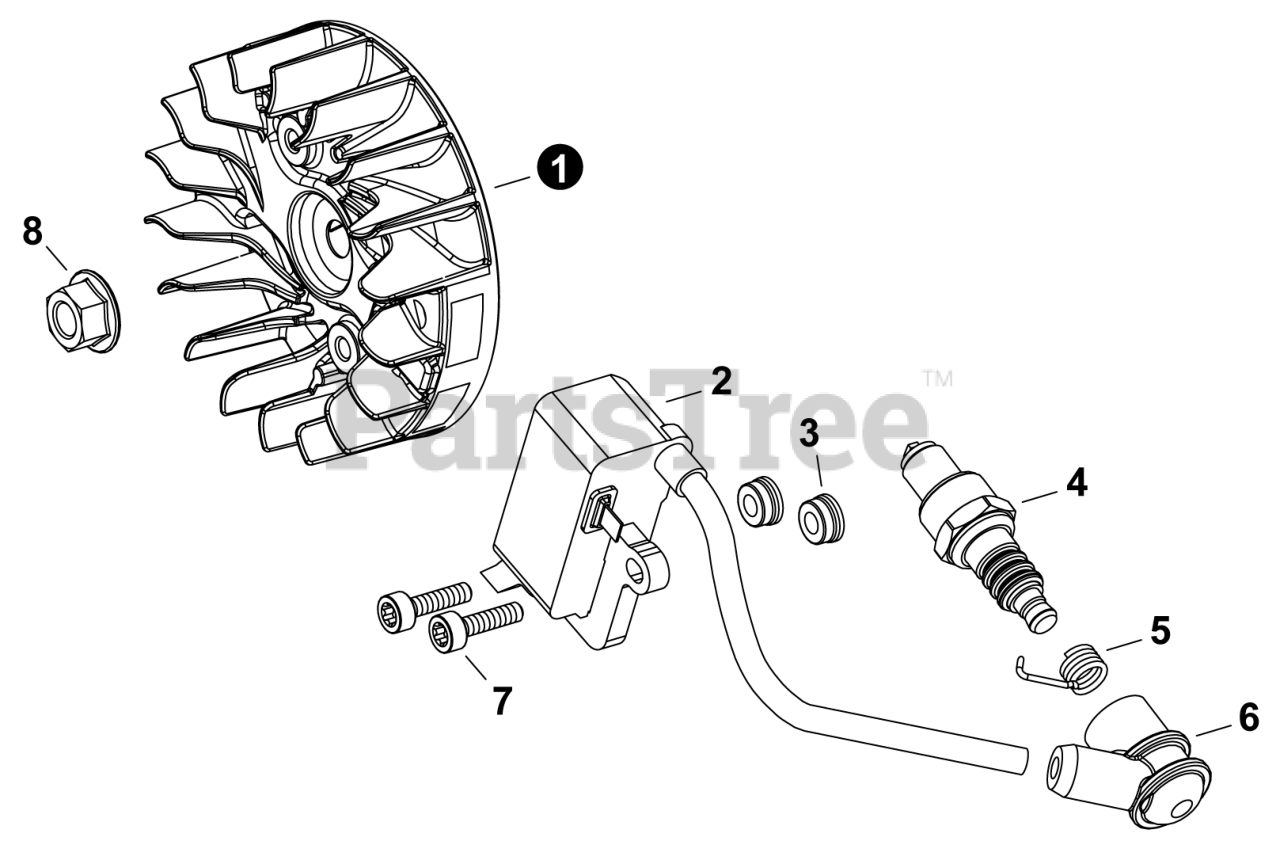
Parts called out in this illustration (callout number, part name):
1	FLYWHEEL
2	COIL, IGNITION
3	COLLAR 4
4	SPARK PLUG - CMR7H
5	TERMINAL, SPARK PLUG
6	CAP, SPARK PLUG
7	BOLT, TORX 4x16
